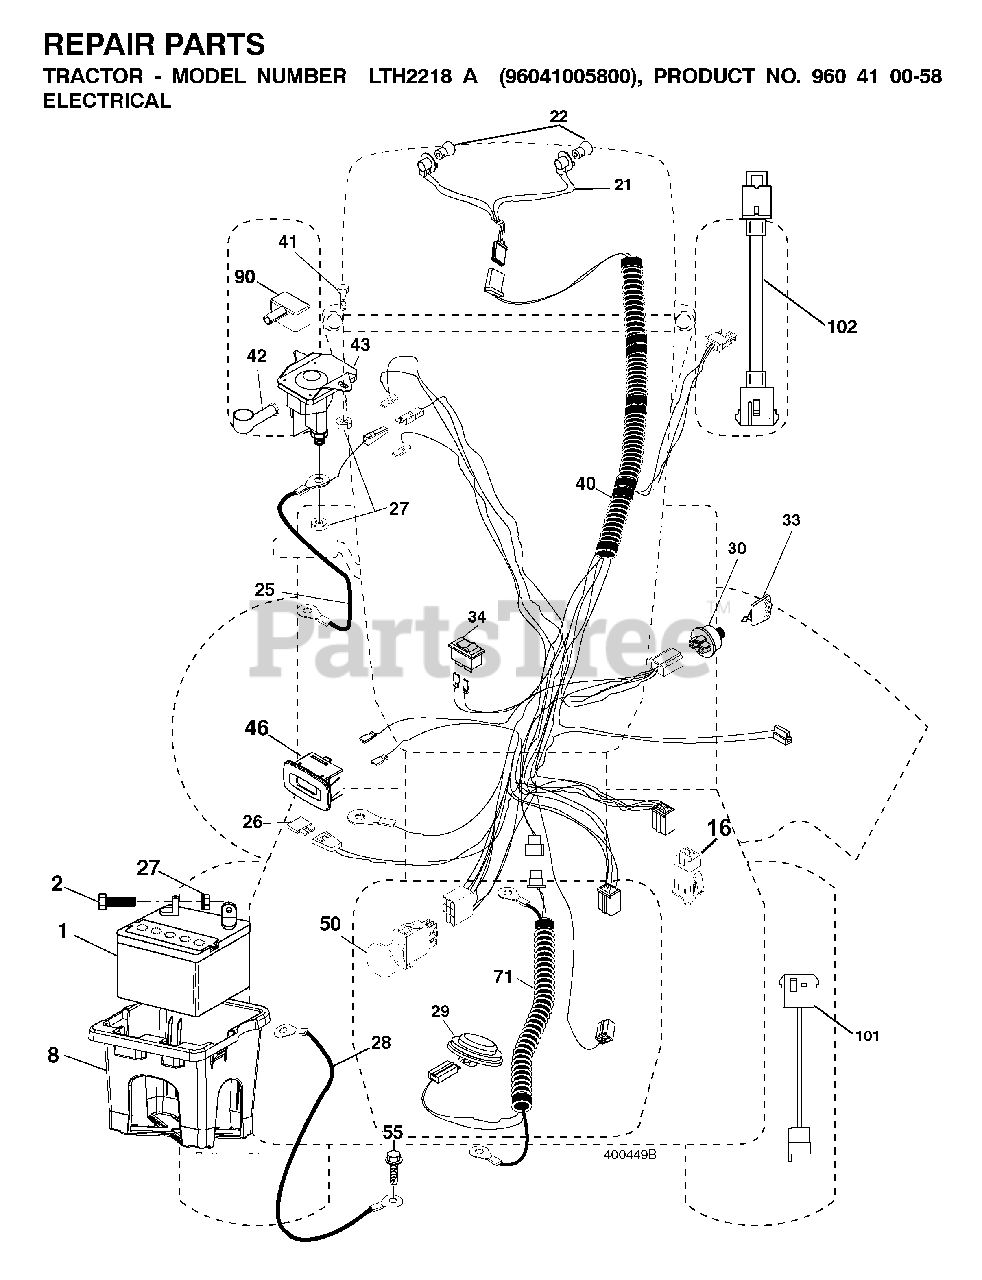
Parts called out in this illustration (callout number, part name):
1	BATTERY 12V .35 AMP
8	BOX.BATTERY.MNT.REAR.L
16	SWITCH INTERLOOK PUSH-IN
21	HARNESS ASSY LIGHT
22	LIGHTBULB
25	CABLE.STARTER.6GA.RED.
26	FUSE 20AMP
27	NUT
28	CABLE.BLACK.18"REAR.BA
29	SWITCH.SEAT.DELTA.OPC.
30	SWITCH.IGN.DELTA.W.LGH.ROS
33	KEY MLD GEN DELTA
34	SWITCH LT
40	HARNESS.IGN.DASH.HUQ/P
41	SCREW
42	TERMINAL COVER
43	SOLENOID.W/BRASS.PLUNG
46	GUAGE.SRVCMNDR.HRMTR.
50	PTO SWITCH
55	SCREW 5/16"
71	HARNESS.IGN.CHASS.TEX.REAR.BAT
90	COVER, TERMINAL BATTERY
101	PIGTAIL.MATNLK.NEW.HAR
102	HARNESS PIGTAIL PCH TEX ROS
